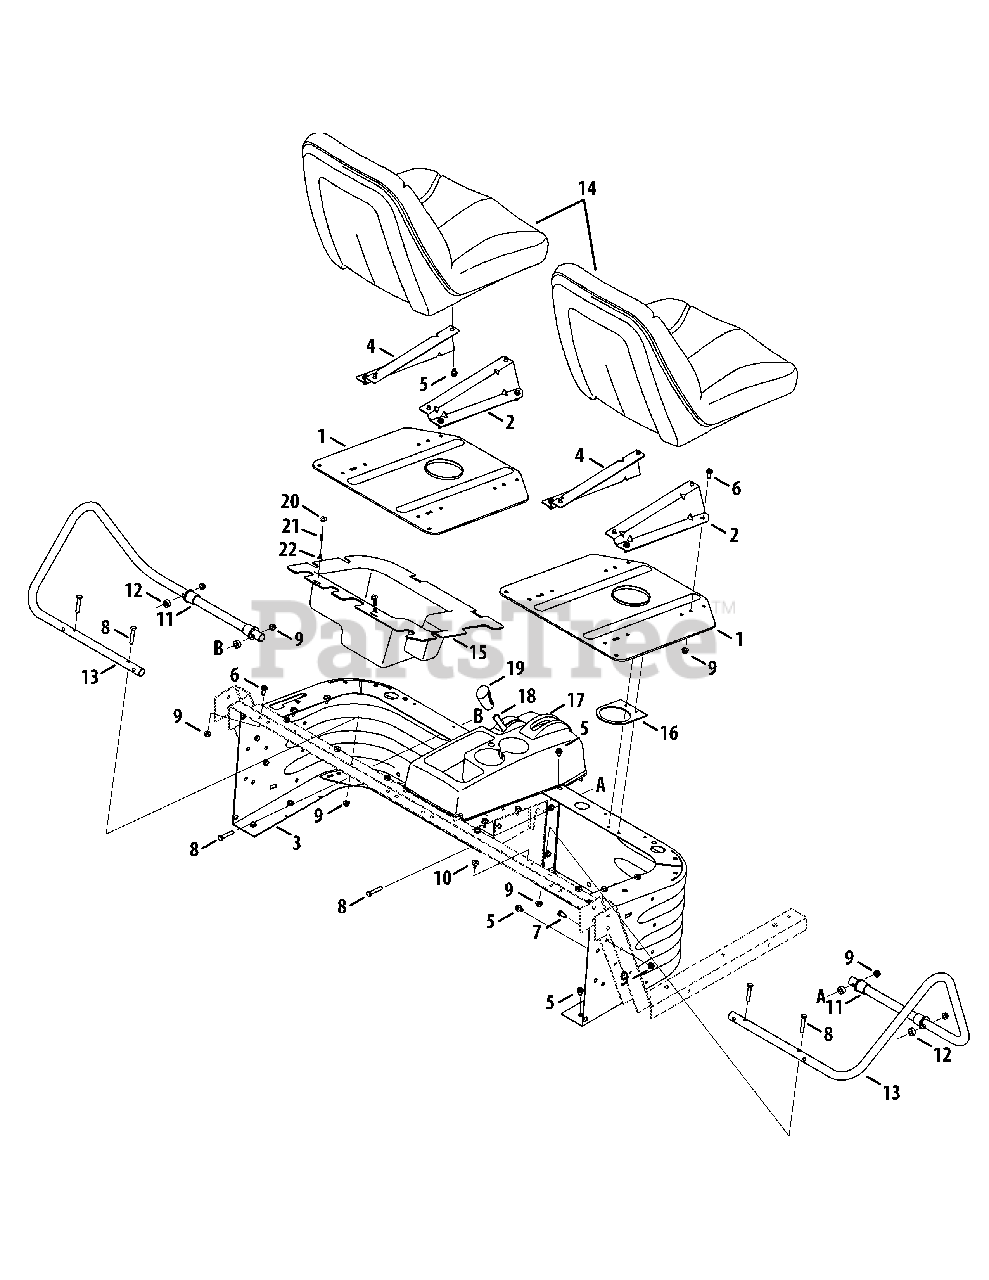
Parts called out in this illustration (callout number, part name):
1	Plate, Seat, Assembly
2	Bracket, Seat, RH
4	Bracket, Seat, LH
5	Screw, TT, 5/16-18 x .500
6	Screw, LD, 5/16-18 x .625
7	Screw, 5/16-18 x .75
8	Screw, 5/16-18 x 1.75
9	Nut, Flange Lock, 5/16-18
10	Bumper, .62 Dia. x .3
11	Bearing, Flange, .894 ID x 1.1315
12	Spacer, .315 x .750 x .375 Lg.
14	Seat, High Back
14	Seat, Sport
15	Tray, Seat Box
16	Bracket, Tube, CVT
17	Seat Console
18	Lever Assembly, Diff Lock
19	Handle, Select
21	Spring Clip
22	Spring, .40 OD x .040 Dia.
